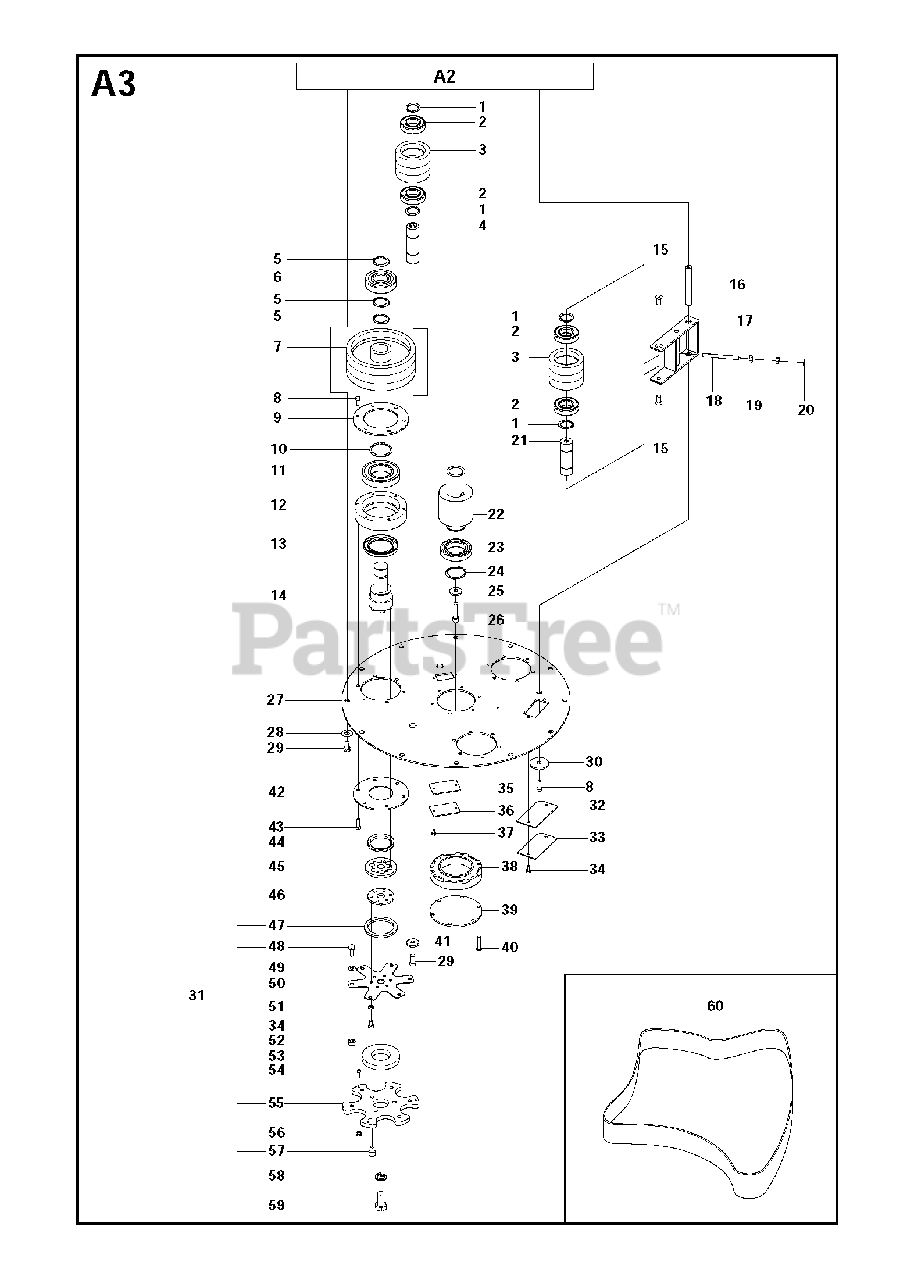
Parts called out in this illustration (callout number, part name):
20	WASHER
28	WASHER
34	SCREW EHHM
40	SCREW EHHM
49	WASHER
52	WASHER
